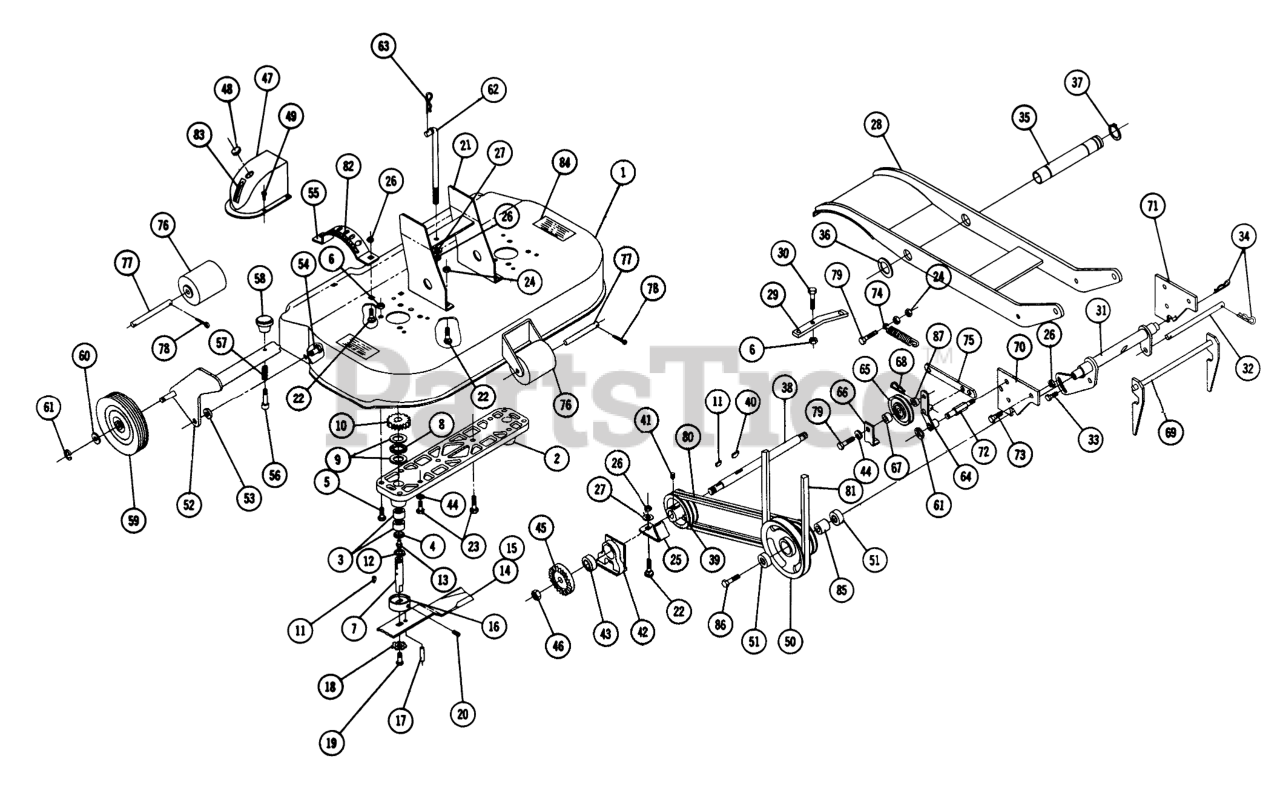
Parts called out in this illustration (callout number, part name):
1	Ass-y Deck
2	Housing
3	NEEDLE BEARING
4	Seal
5	Bolt 5/16-18 x 1
6	Nut-Nylok
7	SPINDLE SHAFT
8	Bearing Thrust
9	Washer-thrust
10	SPUR GEAR
11	WOODRUFF KEY
12	RING-SNAP, EXTERNAL
13	Zerk
14	Blade R.H. 18"
15	Blade L.H. 18"
16	SPINDLE CUP
17	SPIROL ROLL PIN
18	WASHER
19	Bolt 3/8-16 x 7/8
20	Set Screw
21	Ass-y Bracket-Hanger
22	Bolt-3/8-16 x 3/4
23	Bolt 3/8-16 x 1
25	Guard
26	3/8-16 E.S.
27	Washer
28	Ass-y-Drag Link
29	Bracket Spring
30	Bolt 5/16-18 x
31	ASSY HITCH SHAFT R
32	Pin-Hitch
33	Bolt Whizlock 3/8-16 x 5/8
34	Hairpin
35	PIVOT TUBE
36	Washer
37	SNAP RING
38	SHAFT
39	PULLEY
40	Key
41	Set Screw
42	Housing
43	Ball
44	Lockwasher
45	Gear
46	Nut Hex 5/8-18 Thin
47	COVER GEAR
48	PLUG BUTTON
49	SCREW
50	Pulley 3 Groove
51	BALL BEARING
52	Ass-y Support-Wheel
53	WASHER
54	SPECIAL BOLT
55	QUADRANT R
56	PLUNGER
57	Spring
58	KNOB
59	WHEEL ASSY
60	SHIM-WASHER
61	E Ring
62	LIFT ROD R
63	Hairpin
64	Ass-y Idler Arm
65	Pulley
66	BRACKET GUARD
67	BUSHING
68	Hairpin
69	Ass-y Latch & Shaft
70	PLATE R H
71	PLATE-MTG BRKT LH R (NS)
72	Support Idler
73	Bolt 3/8-16 x 1
74	SPRING R
75	Link
76	Roller
77	Shaft
78	Cotter Pin
79	Bolt, 3/8-16 x 1/2
80	V-BELTS - MATCHED PR
81	V BELT
82	Decal-Height Control
83	Decal
84	Decal
85	Spacer
86	Bolt Hex 7/16-14 x 3
87	SPACER
